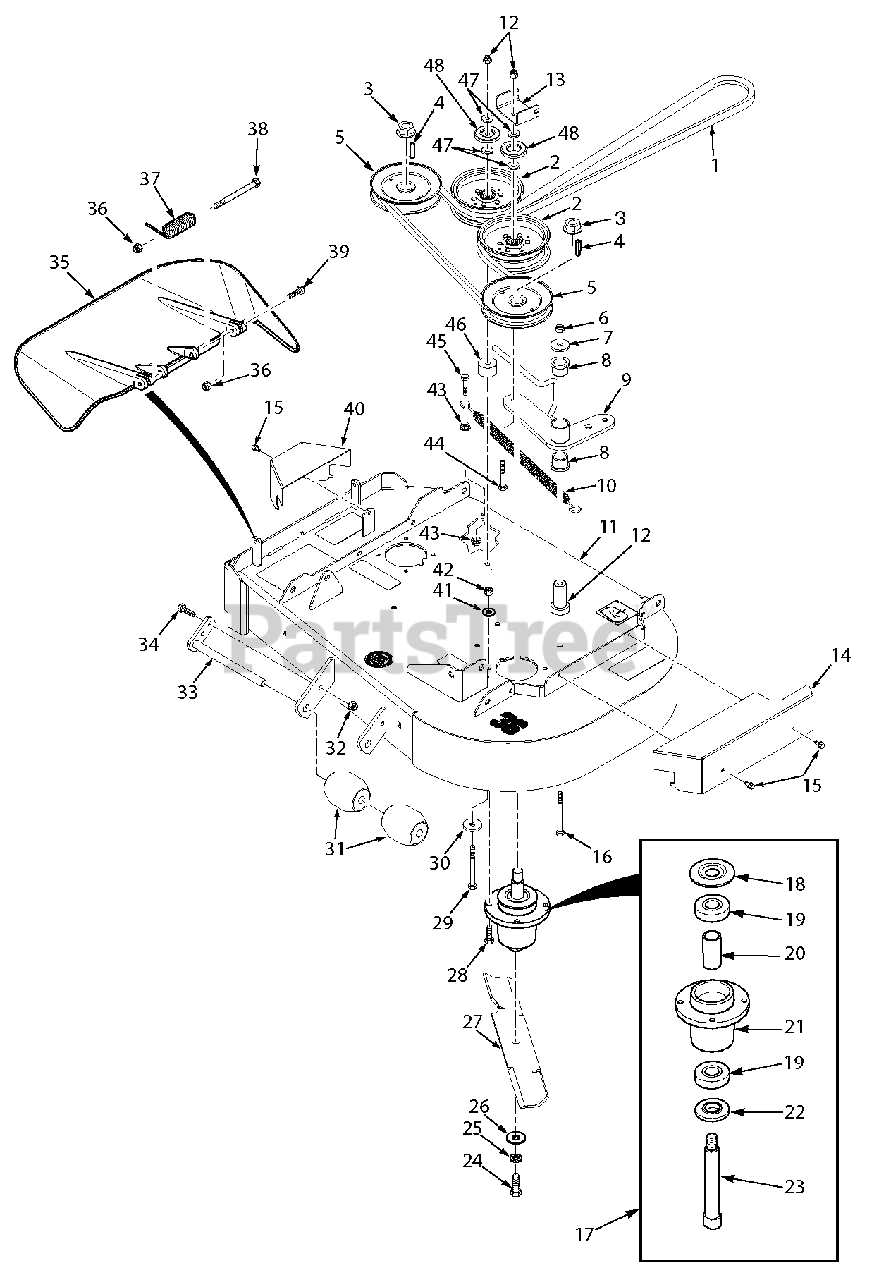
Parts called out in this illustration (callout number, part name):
1	Belt, Cutter Deck
2	Pulley, 5" Idler
3	Nut, 3/4-16 Spiral Lock
4	Key, 1/4 x 1/4 x 1-1/4"
5	Pulley, 5.73" OD - 25mm Bore
6	Nut, 3/8-16 Elastic Stop
7	Flat washer, 1/4-.266 x .875 x .125
8	Bearing, 1" ID
9	Pivot, Idler
10	Spring, Cutter Deck Idler
11	Cutter Deck w/Decals, SMLZ-36
12	Pivot, Idler
13	Bracket, Belt Guide
14	Belt Cover LH SMZL-36
15	Screw, 1/4-20 x .375"
16	Bolt, Hex Head 3/8-16 x 4.00
17	Spindle Assembly
18	Debris Shield
19	Bearing
20	Spacer
21	Spindle Housing
22	Protector, Bearing
23	Shaft, Spindle
24	Bolt, Hex Head 5/8-11 x 1-1/2"
25	Lockwasher, 5/8"
26	Flatwasher, 5/8-.688 x 1.75 x .134 HD
27	Cutter Blade, 18"
28	Bolt, Hex Head 5/16-18 x 1-1/2"
29	Bolt, Hex Head 3/8-16 x 3-1/2"
30	Flatwasher, 3/8-.406 x 2.250 x .188
31	Wheel, Anti-Scalp
32	Nut, 5/16-18 Flange Elastic Stop
33	Shaft Weldment, Guide Roller
34	Bolt, Hex Head 5/16-18 x 1"
35	Discharge Chute
36	Nut, 5/16-18 Elastic Stop
37	Spring, Discharge Chute
38	Bolt, Hex Head 5/16-18 x 4-3/4"
39	Bolt, Hex Head 5/16-18 x 1-3/4"
40	Belt Cover, RH SMZL-36
41	Lockwasher, 5/16"
42	Nut, 5/16-18 Elastic Stop
43	Nut, 3/8-16 Serrated Flange
44	Bolt, Hex Head 1/4-20 x 2.00
45	Bolt, Hex Head 3/8-16 x 1-1/2"
46	Spacer
47	Flatwasher, 3/8-.391 x .938 x .105 HD
48	Dust Shield
